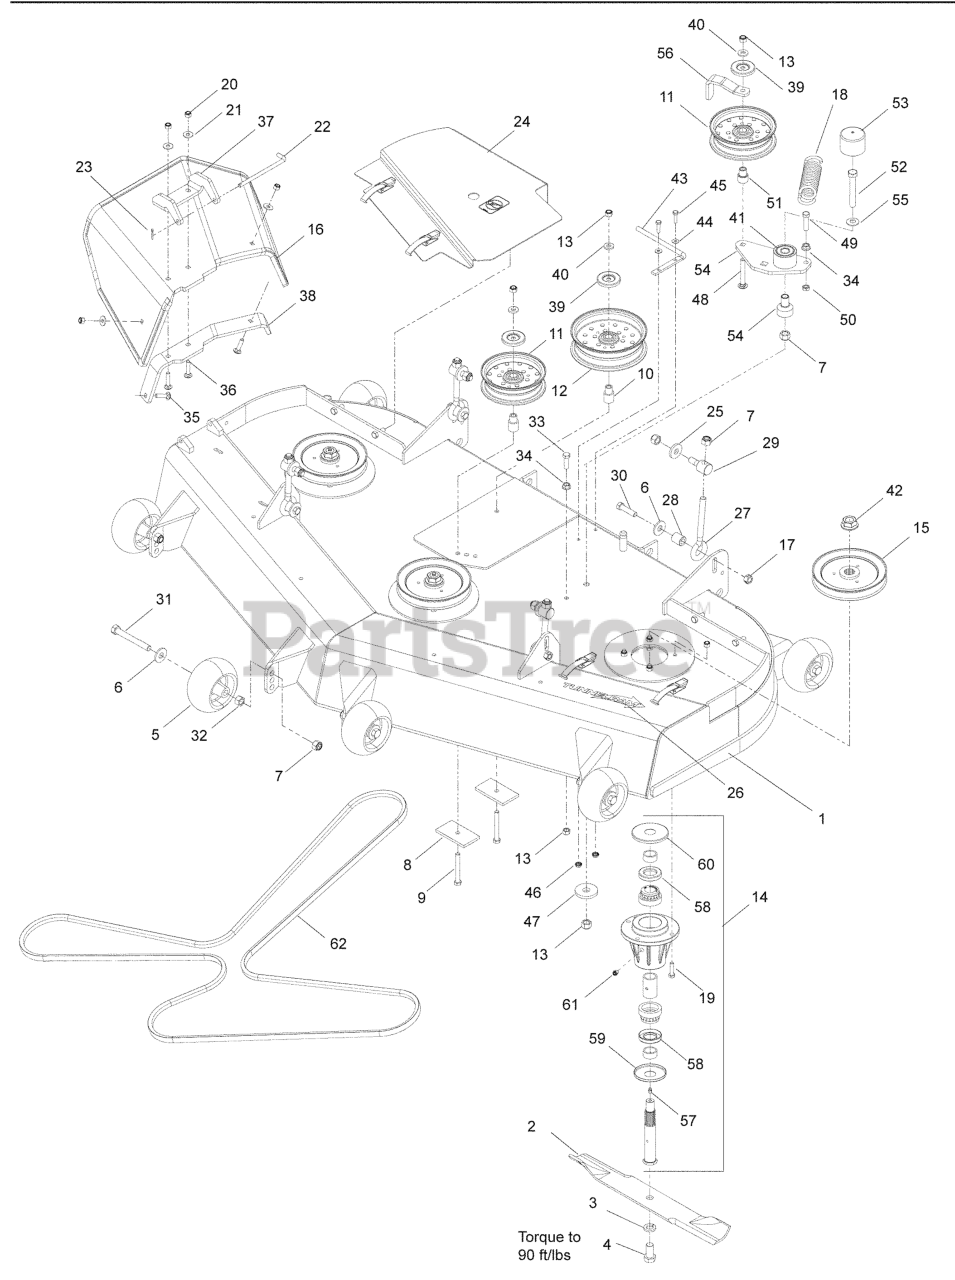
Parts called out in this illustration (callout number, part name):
1	DECK W/DECALS 61" HUS
2	BLADE OEM 21" (61" DECK)
3	LOCKWASHER 5/8
4	HCS 5/8F X 1 1/4
5	GAUGE WHEEL
6	WASH USS FLAT 1/2
7	NUT 1/2-13 HEX NYLOC ZD
8	SUPPORT PLATE
9	HCS 3/8C X 3
10	IDLER BUSHING
11	IDLER PULLEY
12	PULLEY - IDLER, 6IN WIDE
13	NUT 3/8-16 NYLOC
14	HOUSING ASM, 52/61
15	PULLEY, 61
16	CHUTE, RUBBER DISCHARGE 52/61"
17	NUT 7/16C CENTERLOCK
19	HCS 5/16C X 1 1/4
20	NUT 5/16 NYLOC
21	WASHER 5/16 FLAT
22	PIN, CHUTE PIVOT
23	RP_COTTER PIN 1/8 X 3/4
24	SUB ASM, 61 BELT SHIELD RH
25	WASHER-.533IDX1.37OD
26	DECAL, TUNNEL RAM 8"
29	SWIVEL, DECK HEIGHT ADJ
30	HCS 7/16 - 14 X 1 3/4
31	HCS 1/2-13 X 4 GR 5 ZD
32	NUT HEX 1/2
33	HCS 3/8C X 1 1/4 GR5
34	NUT 3/8C WHIZ
35	BOLT, CARRIAGE 5/16X1-1/4
36	RHSNB 5/16-18 X 1-1/2 GR 5 ZD
37	PIVOT BRACKET - RUBBER CHUTE
38	BRACKET, REINF-CHUTE
39	DUST SHIELD
40	WASHER, 3/8 THICK
41	ARM-IDLER W/BRG
42	NUT FLANGE 3/4-16
43	BELT GUIDE
44	WASHER 1/2 FLAT
45	HCS 1/4 X 1
46	NUT 1/4-20 HEX FLG LK ZD
47	WASHER, SUPPORT
48	RHSNB 3/8-16 X 2.75
49	HCS 3/8-16 X 1-1/2
50	NUT 3/8-16 HEX JAM
51	BUSHING, IDLER
52	HCS 1/2C X 3 1/4
53	CAP, VINYL
54	PIVOT, BEARING
55	CONTACT BELLSPR 1/2
56	GUIDE, BELT
57	ZERK
58	SHAFT SEAL
59	BOTTOM DUST CAP
60	TOP DUST CAP
61	PLUG-VENTED
62	BELT, DECK 61
